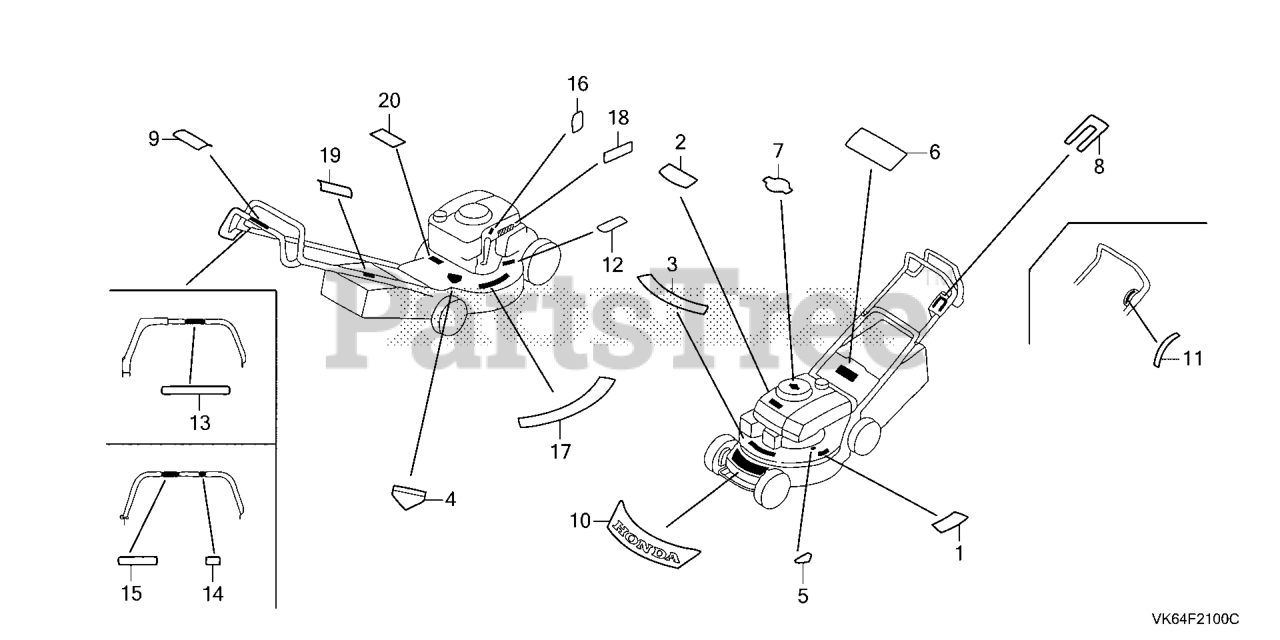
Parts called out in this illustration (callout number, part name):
2	MARK, EMBLEM
4	LABEL C, HOUSING CAUTION
6	LABEL, WARNING (ENGLISH)
8	MARK, THROTTLE INDICATION (ENGLISH)
9	MARK, CLUTCH INDICATION (ENGLISH)
10	MARK, HONDA
12	LABEL, HEAT WARNING
14	MARK, BLADE CONTROL
15	MARK, BLADE CONTROL (ENGLISH)
16	MARK, OIL CAUTION
20	LABEL, WARNING
